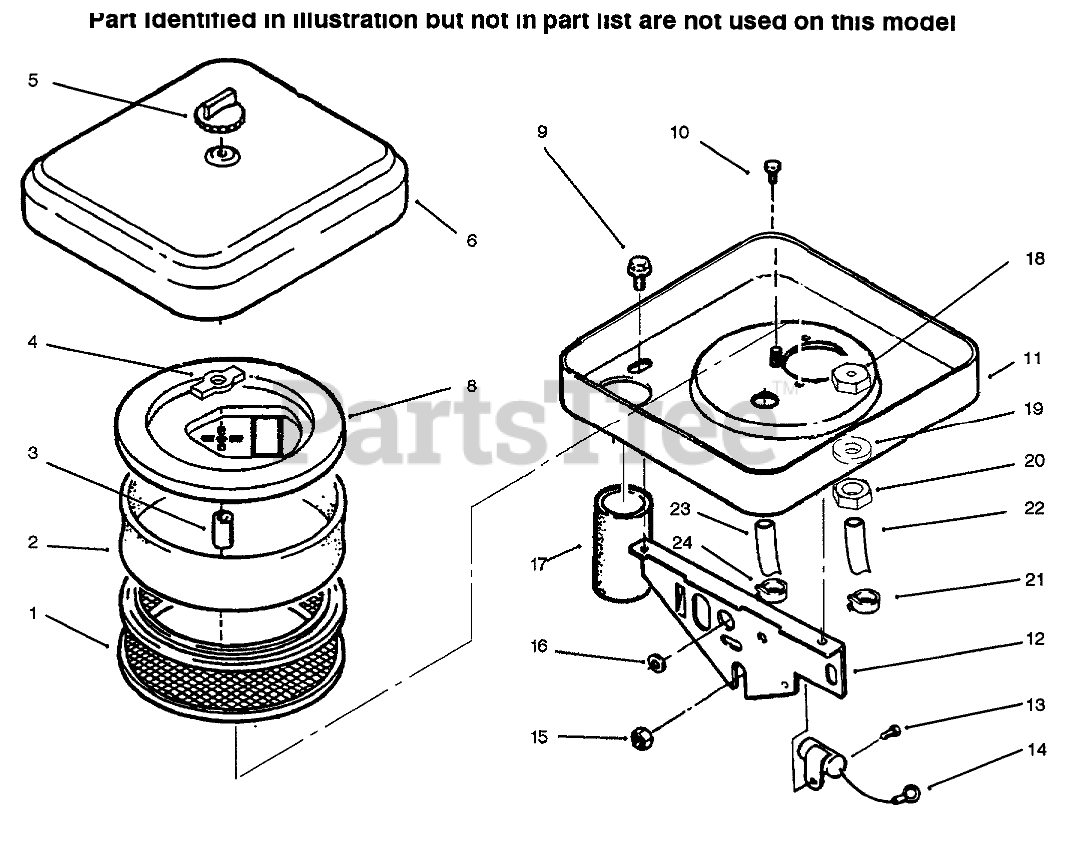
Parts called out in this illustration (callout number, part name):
1	AIR-CLEANER ELEMENT
2	AIR CLEANER ELEMENT
3	SPACER-1" LG
4	SPACER-RUBBER
6	CHROME-AIR CLEANER
8	ELEMENT COVER KIT
9	SCREW-TAPPING
10	MACHINE SCREW
11	AIR-CLEANER HOUSING
12	SUPPORT-AIR CLEANER
13	SCREW #10-32 X 5/8
14	CONDENSER
16	GROMMET
17	AIR INTAKE TUBE
18	Fitting-Barbed
19	HOSE FITTING GASKET
20	TAPPET NUT
21	CLAMP-HOSE
23	Clamp
24	Hose
